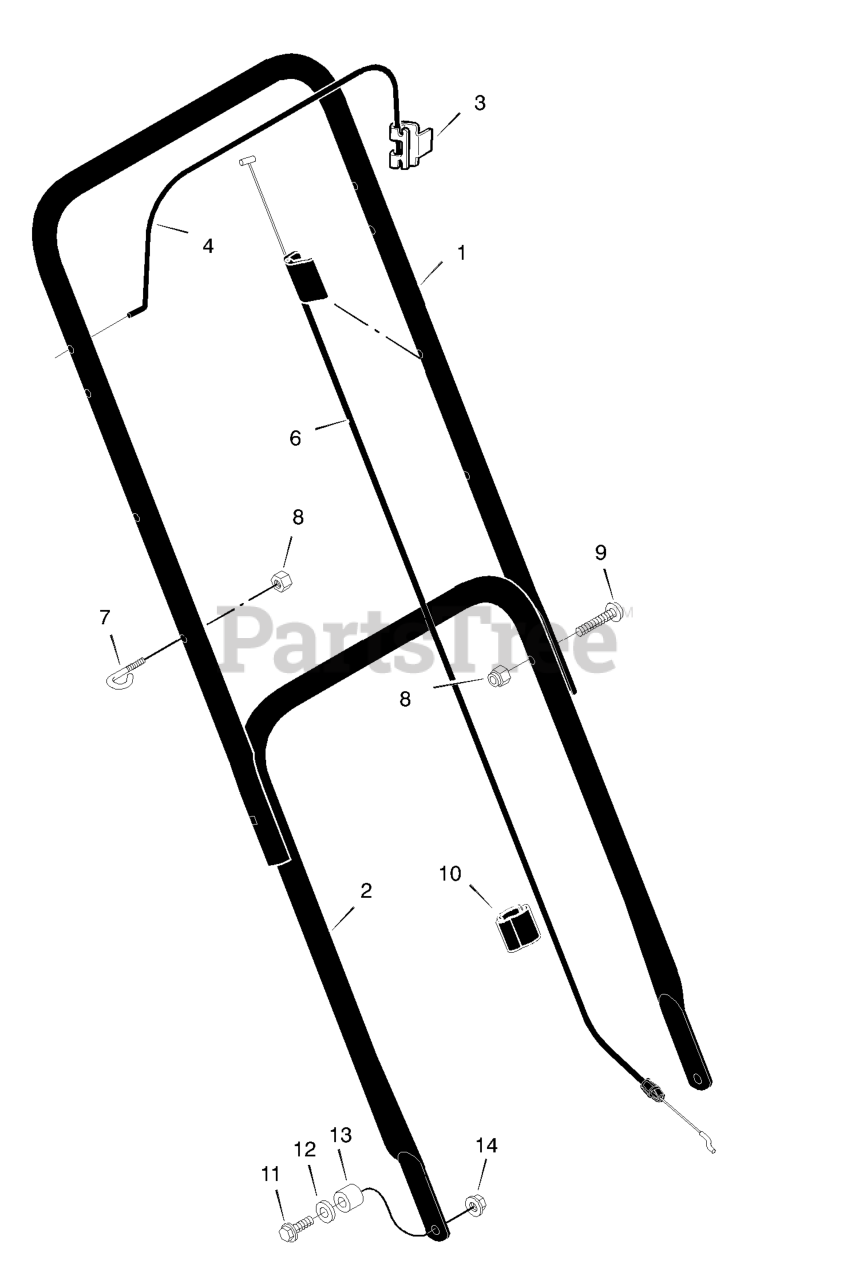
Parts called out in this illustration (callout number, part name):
1	Handle, Upper (Black)
2	Handle, Lower (Black)
3	Bracket, Stop Lever
4	Lever, Stop
6	Engine Stop Cable
7	GUIDE, ROPE
8	Locknut
10	Clip, Cable
11	Bolt
12	Washer
14	Nut
